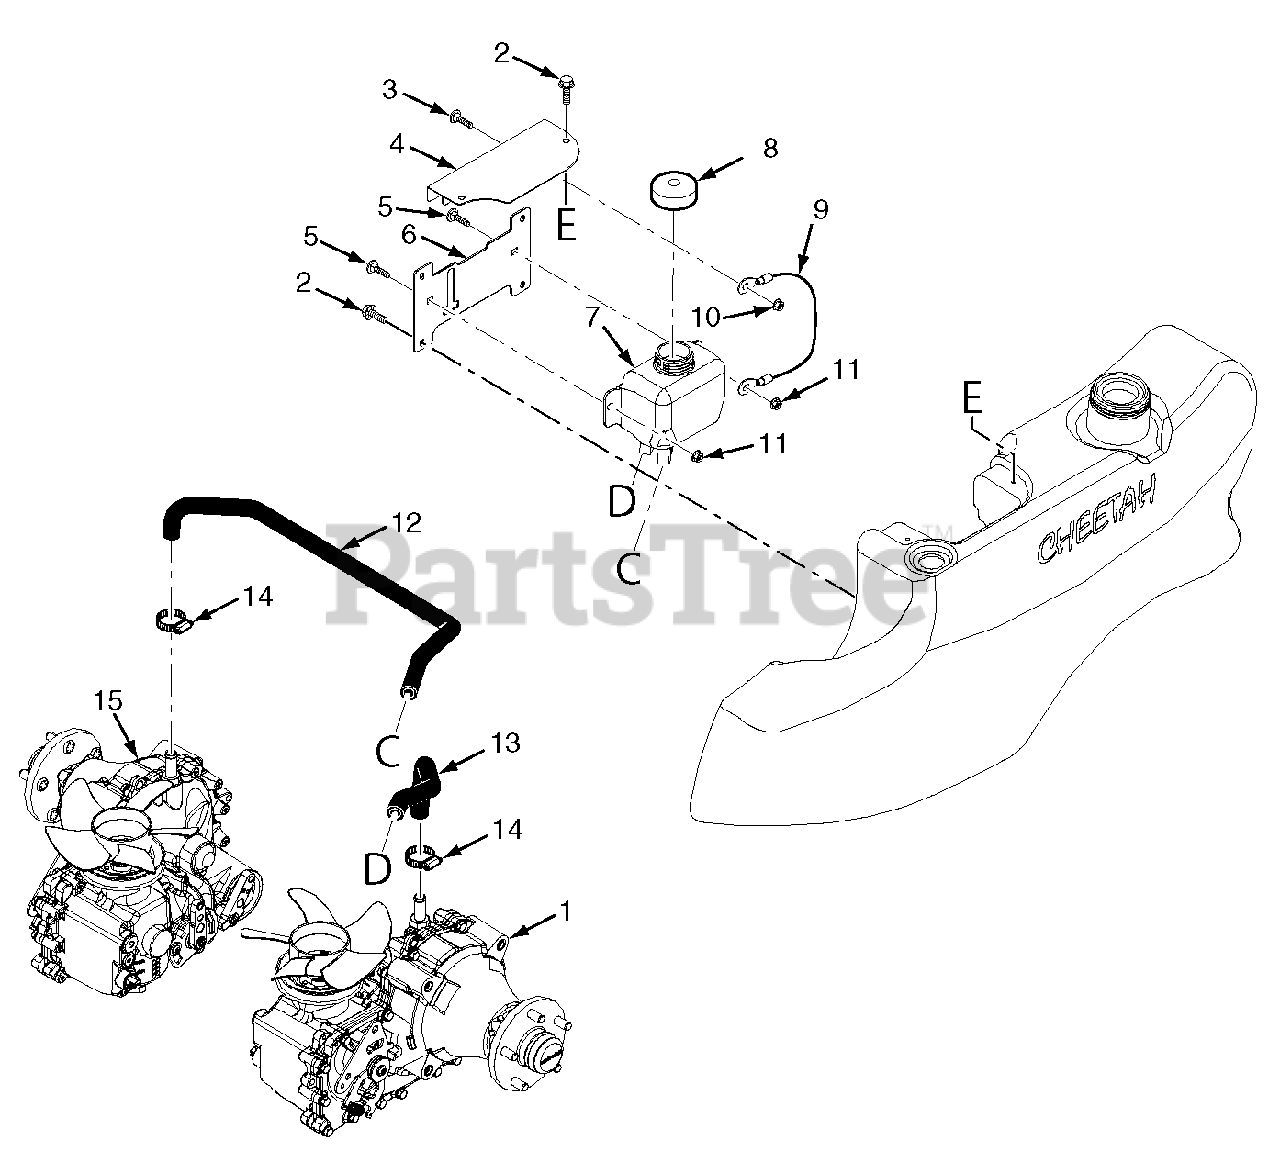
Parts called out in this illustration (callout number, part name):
1	Transaxle, LH
2	Bolt, Hex Head 1/4-20 X 1/2" Serrated Flange
3	Bolt, Carriage 1/4-20 x 3/4"
4	Cover, Oil Reservoir
5	Bolt, Carriage 5/16-18 x 3/4"
6	Plate, Hydro Tank Mount
7	Hydraulic Tank Assembly
8	Cap, Hydraulic Tank
9	Lanyard, Hydraulic Tank
10	Nut, Elastic Stop 1/4-20
11	Nut, FLG HH Elastic Stop 5/16-18
12	Hose, RH Transaxle
13	Hose, LH Transaxle
14	Clamp, 1" Max Dia.
15	Transaxle, RH
